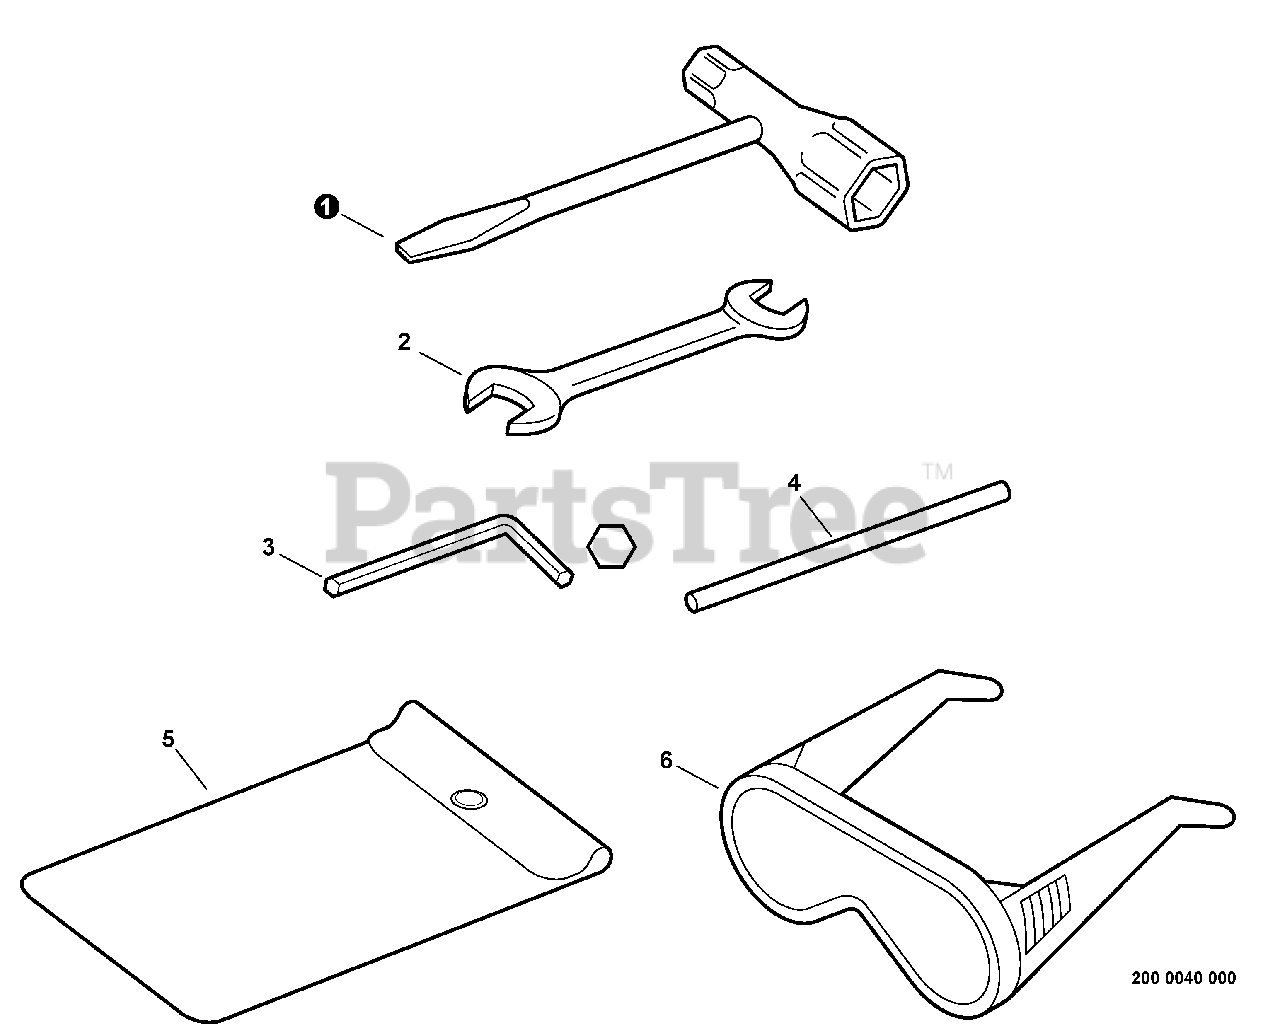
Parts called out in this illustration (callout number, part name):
1	T-WRENCH 17x-19 L200
2	SPANNER 8×10
3	WRENCH, ALLEN 4 MM
4	TOOL, LOCKING 5×120 MM
5	BAG, TOOL
6	GLASSES, SAFETY
